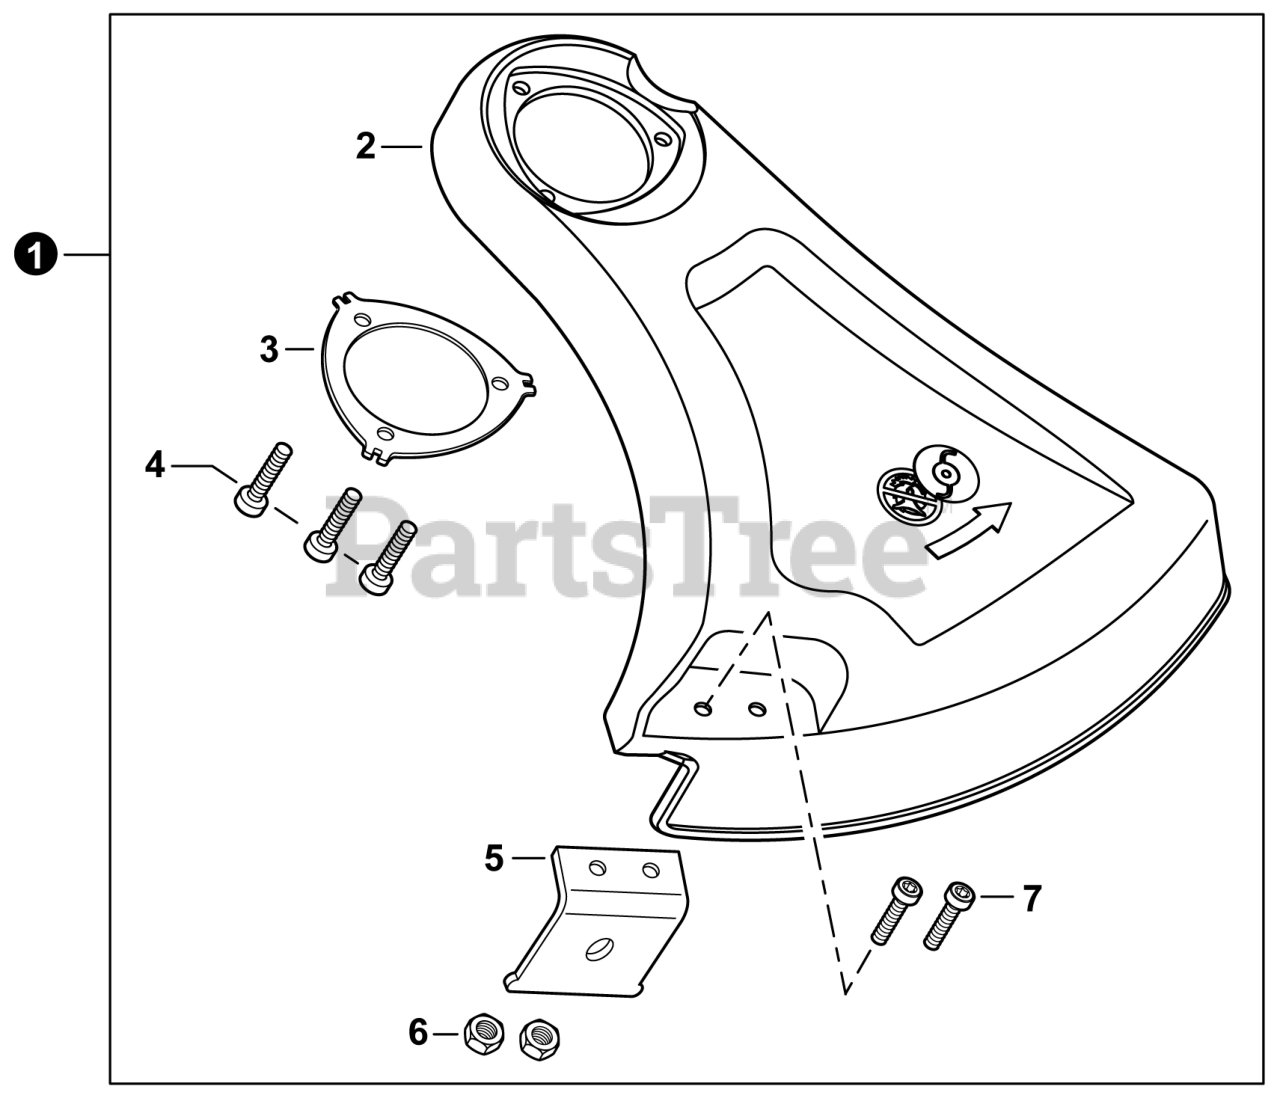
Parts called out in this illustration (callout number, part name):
1	SHIELD ASSY, DEBRIS
2	SHIELD, DEBRIS
3	PLATE, SHIELD
4	BOLT, TORX 5x16
5	CUTTER, LINE
6	NUT M5
7	BOLT, TORX 5x12
